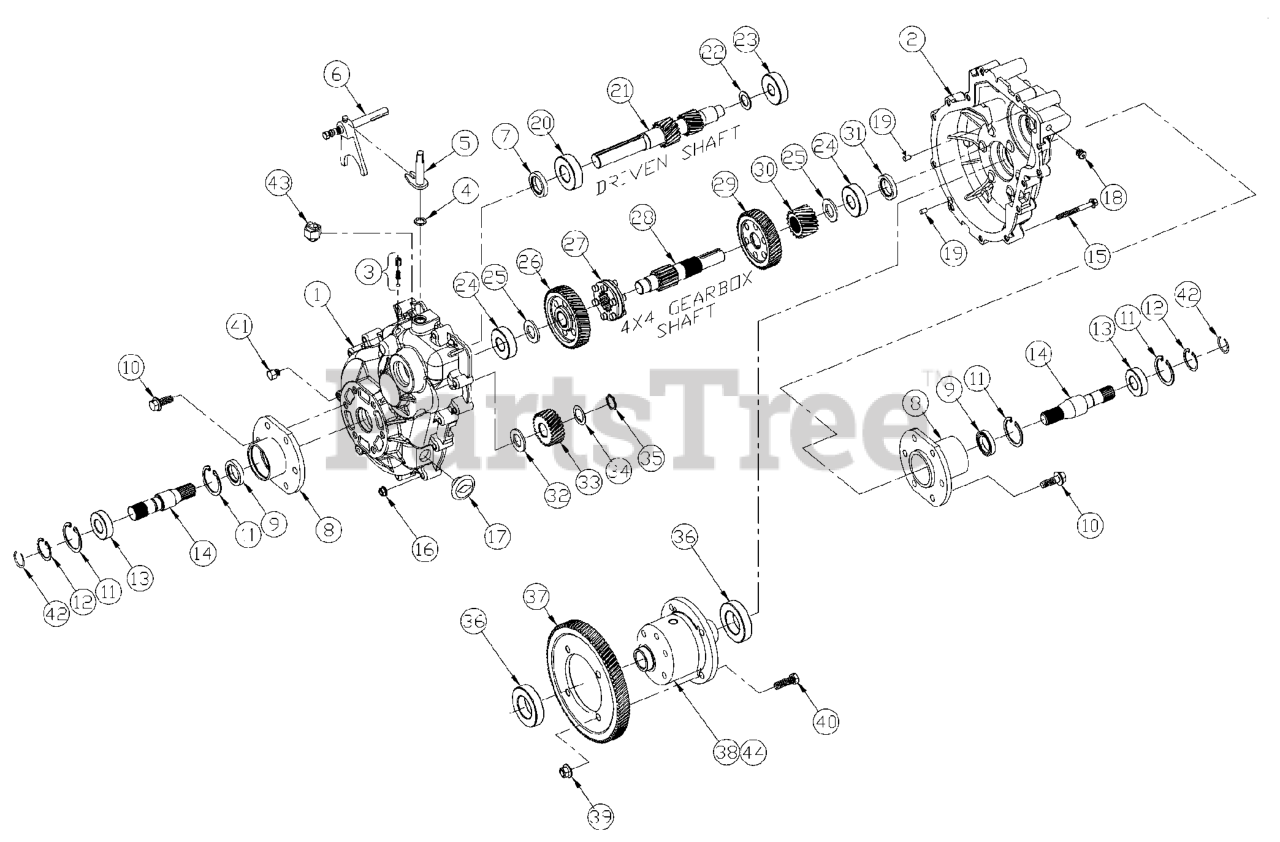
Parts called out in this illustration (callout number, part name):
1	DANA HOUSING AND SHAFT ASSEMBLY
2	DANA HOUSING Ð AXLE FIN
3	DANA KIT, DETENT
4	DANA SEAL Ð OIL
5	DANA ACTUATOR ASSEMBLY
6	DANA SHIFT ROD SUB-ASSEMBLY
7	DANA SEAL Ð OIL
8	REAR TUBE ASSEMBLY
9	SEAL Ð OIL
10	DANA SCREW Ð FLG HEAD
11	DANA RING, RETAINING
12	RING Ð RETAINER
13	BEARING Ð BALL SINGLE
14	SHAFT Ð AXLE, FIN
15	DANA SCREW Ð FLG HEAD
16	DANA NUT Ð LOCK
17	DANA PLUG Ð RUBBER
18	DANA VENT PLUG
19	DANA PIN Ð DOWEL
20	DANA BEARING 6205
21	DANA SHAFT Ð INPUT FIN
22	DANA KIT, SHIM
23	DANA BEARING Ð 6303 BALL SINGLE
24	DANA BEARING Ð 6204 BALL SINGLE
25	DANA SPACER Ð FLAT
26	DANA GEAR ASSEMBLY Ð FORWARD
27	DANA GEAR Ð CLUTCH
28	DANA SHAFT Ð INTERMEDIATE FIN
29	DANA GEAR ASSEMBLY Ð REVERSE
30	DANA GEAR Ð HELICAL FIN
31	DANA SEAL Ð OIL
32	DANA WASHER Ð THRUST
33	DANA GEAR ASSEMBLY Ð IDLER
34	DANA WASHER Ð THRUST
35	DANA RING Ð SNAP
36	DANA BEARING 6007
37	DANA GEAR Ð HELICAL FIN
38	DIFFERENTIAL, AUTO-LOCK
39	DANA NUT Ð LOCK
40	DANA BOLT Ð HEX
41	DANA DRAIN PLUG
42	RETAINER Ð SHAFT, AXLE
43	SWITCH, NEUTRAL, DANA GBOX
44	AUTO-LOK KIT* (Kit includes 1 ea. #38, 4 ea. #39 & 4 ea. #40)
